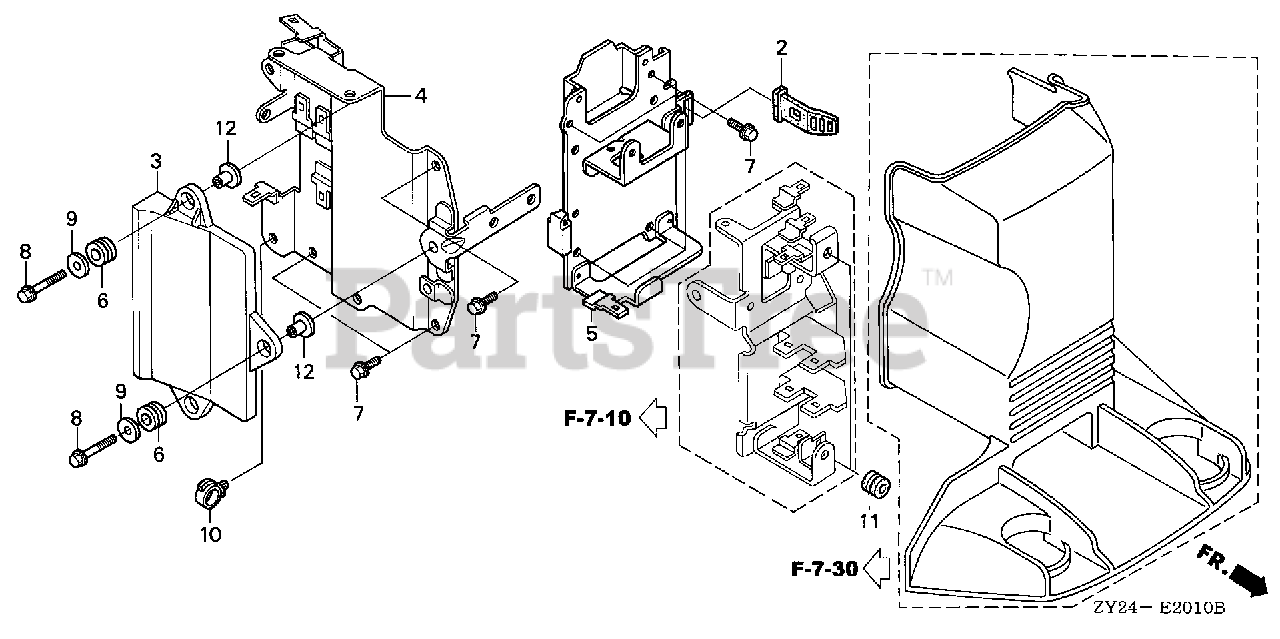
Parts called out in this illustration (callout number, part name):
2	BELT, COVER
3	CONTROL UNIT, ELECTRONIC
4	BRACKET, PCM
5	BRACKET, ELECTRIC PARTS
6	RUBBER, UNIT
7	BOLT, FLANGE (6X14) (CT200)
8	BOLT, FLANGE (6X28)
9	WASHER, PLAIN (22X6X1.6)
10	CLIP, WIRE HARNESS (25MM)
11	RUBBER, TANK CUSHION
12	COLLAR, UNIT
